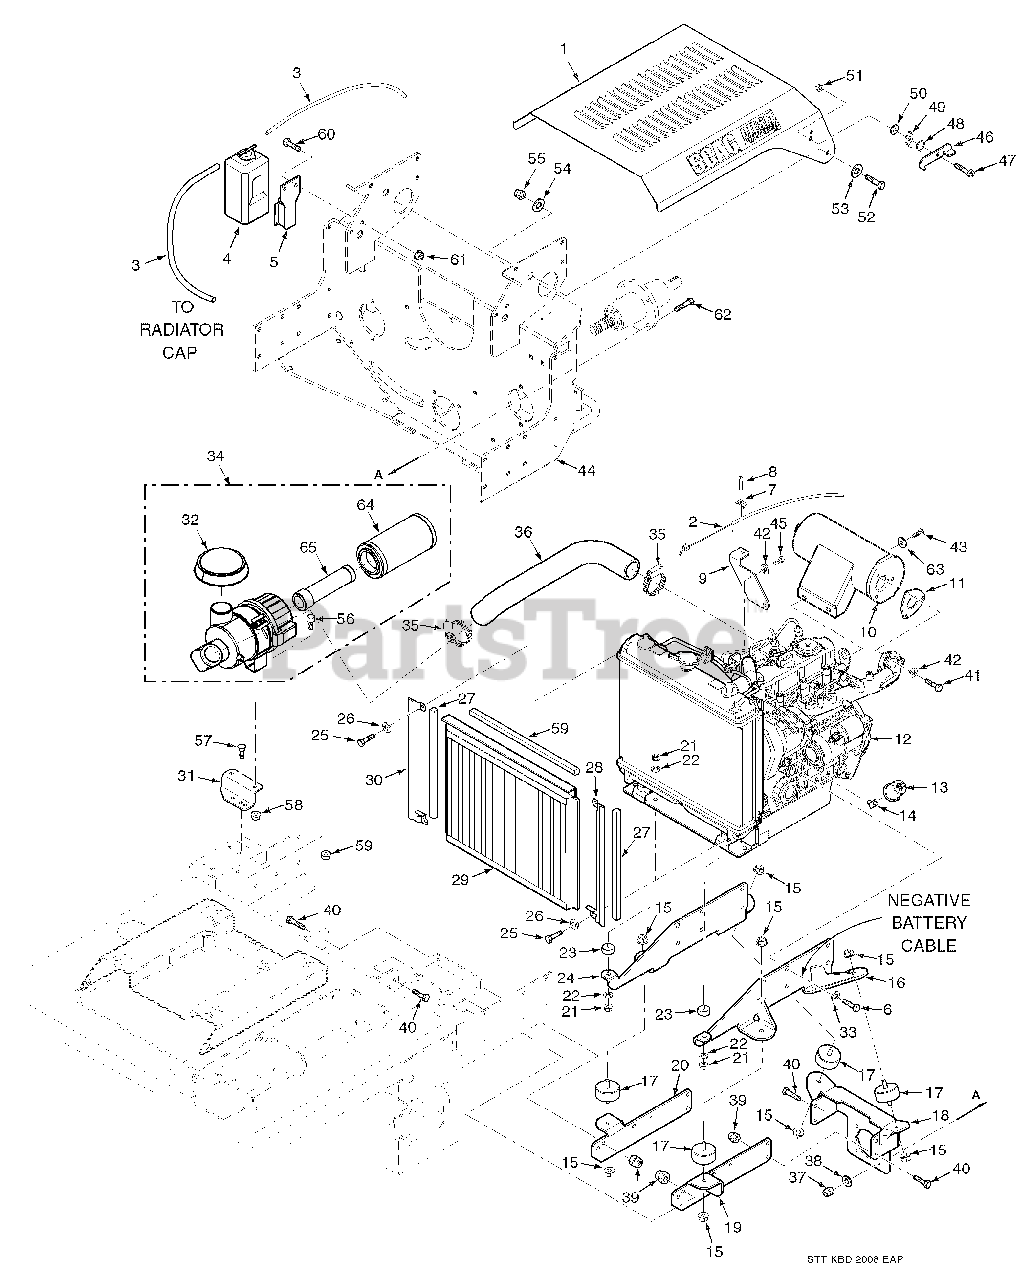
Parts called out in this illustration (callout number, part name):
1	Hood Assembly
2	Throttle Cable
3	Hose, Over Spill Bottle
4	Over Spill Bottle
5	Mounting Bracket, Over Spill Bottle
6	Bolt, Metric Hex Head M10-1.25 x 25LG
7	Clamp
8	Screw, Self Tapping
9	Bracket, Control Mount
10	Muffler, Kubota
11	Gasket, Muffler
12	Engine, Kubota
13	Oil Pressure Sender
14	Elbow, 45 Degree
15	Nut, Serrated Flange 5/16-18
16	Mounting Bracket Weldment LH
17	ISO Mount
18	Plate, Rear Engine Mount
19	Plate, Engine Mount LH
20	Plate, Engine Mount RH
21	Nut, Metric Hex M8-1.25
22	Lockwasher, 5/16” Spring
23	Rubber ISO Mount, Radiator
24	Mounting Bracket Weldment RH
25	Capscrew, Metric M6-1.0 x 16
26	Lockwasher, 1/4” Spring
27	Foam, Radiator Screen
28	Debris Screen Track LH
29	Debris Screen Assembly
30	Debris Screen Track RH
31	Bracket, Air Cleaner Mount
32	Rain Cap
33	Lockwasher, 7/16” Spring
34	Air Filter Assembly
35	Clamp, 2-1/4” Max. Dia.
36	Hose, Air Intake
37	Nut, Elastic Stop 5/16-18 Grade 8
38	Lockwasher, 5/16” Spring
39	Nut, Elastic Stop 3/8-16
40	Bolt, Hex Head 3/8-16 x 1”
41	Bolt, Metric Hex Head M8-1.25 x 30LG
42	Lockwasher, 5/16” Spring
43	Bolt, Metric Hex Head M8-1.25 x 25LG
44	Pump Mounting Plate Weldment
45	Bolt, Metric Hex Head M8-1.25 x 20LG
46	Latch, Hood
47	Bolt, Shoulder 5/16-18 x 1/2”
48	Spring, Hood Latch
49	Lock, Hood Latch
50	Flatwasher, 3/8-.391 x .938 x .105
51	Nut, Center Lock 5/16-18
52	Bolt, Hex Head 3/8-16 x 1-3/4”
53	Flatwasher, 3/8-.391 x .938 x .105
54	Flatwasher, 3/8-.406 x 1.50 x 7 Gauge
55	Nut, Elastic Stop 3/8-16
56	Bolt, Hex Head Serr. Flange 5/16-18 x 3/4”
57	Bolt, Carriage 5/16-18 x 3/4”
58	Nut, Serrated Flange 5/16-18
59	Foam, Radiator Screen Upper
60	Bolt, Hex Head Serr. Flange 5/16-18 x 3/4”
61	Nut, Serrated Flange 5/16-18
62	Bolt, Hex Head 5/16-18 x 1-3/4” Grade 8
63	Flatwasher, SAE 5/16-.344 x .688 x .065
64	Air Filter, Outer
65	Air Filter, Inner
